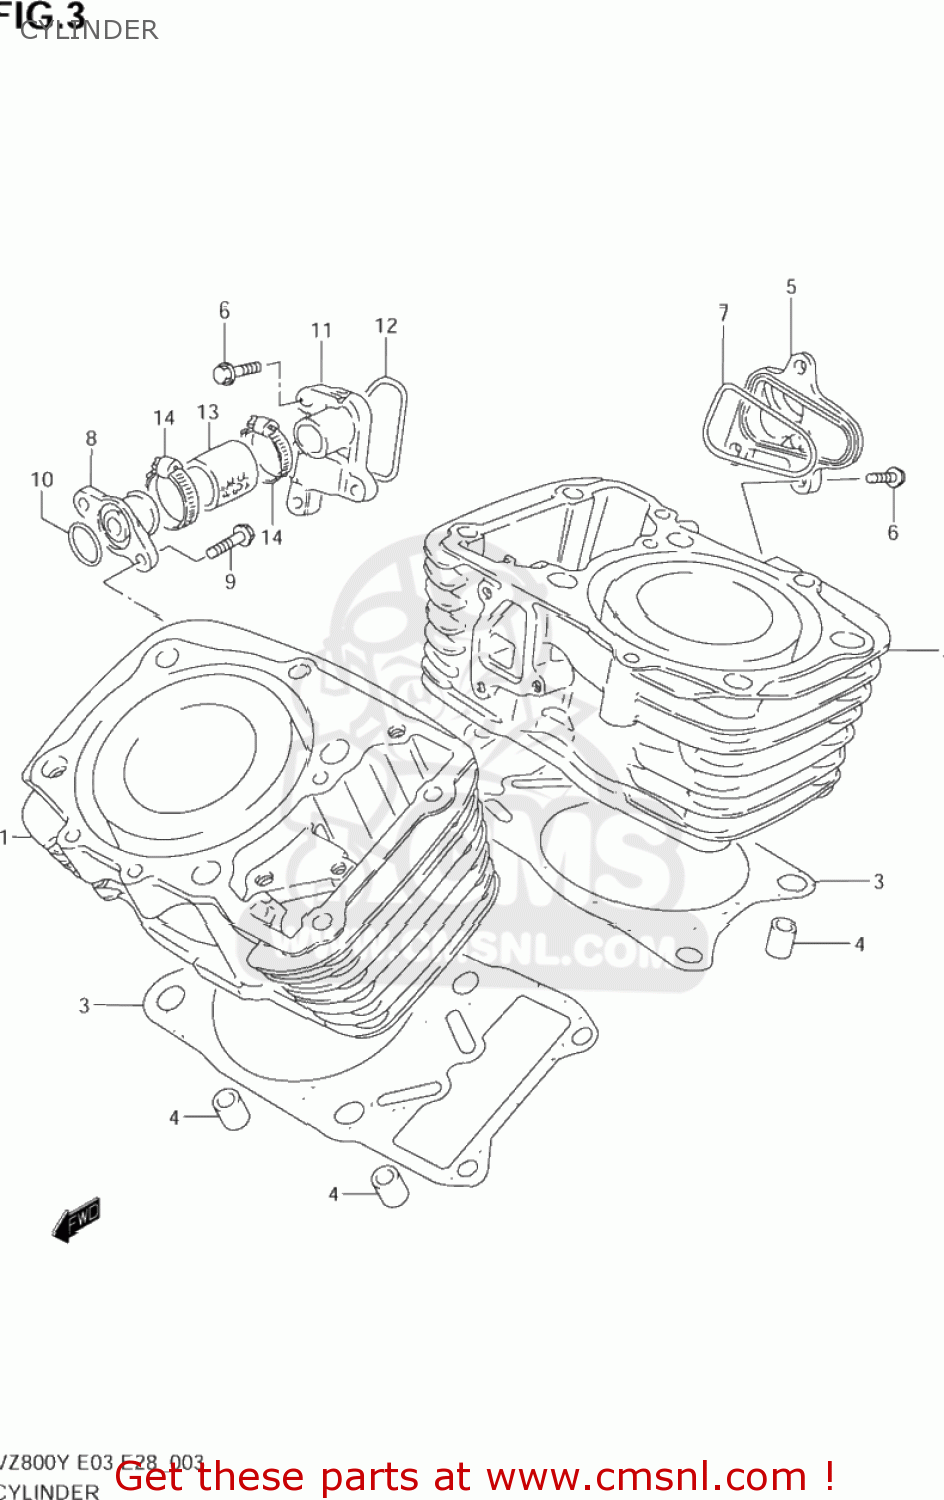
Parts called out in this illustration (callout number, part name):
1	CYLINDER,FR
2	CYLINDER,RR
3	GASKET,CYLINDER (NAS)
4	PIN
5	CHAMBER,WATER INLET
6	BOLT
7	O RING,INLET WATER CHAMBER
8	UNION,WATER INLET
9	BOLT
10	O RING(D:2.4,ID:15.8)
11	CHAMBER,WATER OUTLET
12	O RING,OUTLET WATER CHAMBER
13	HOSE,RADIATOR INLET
14	CLAMP
